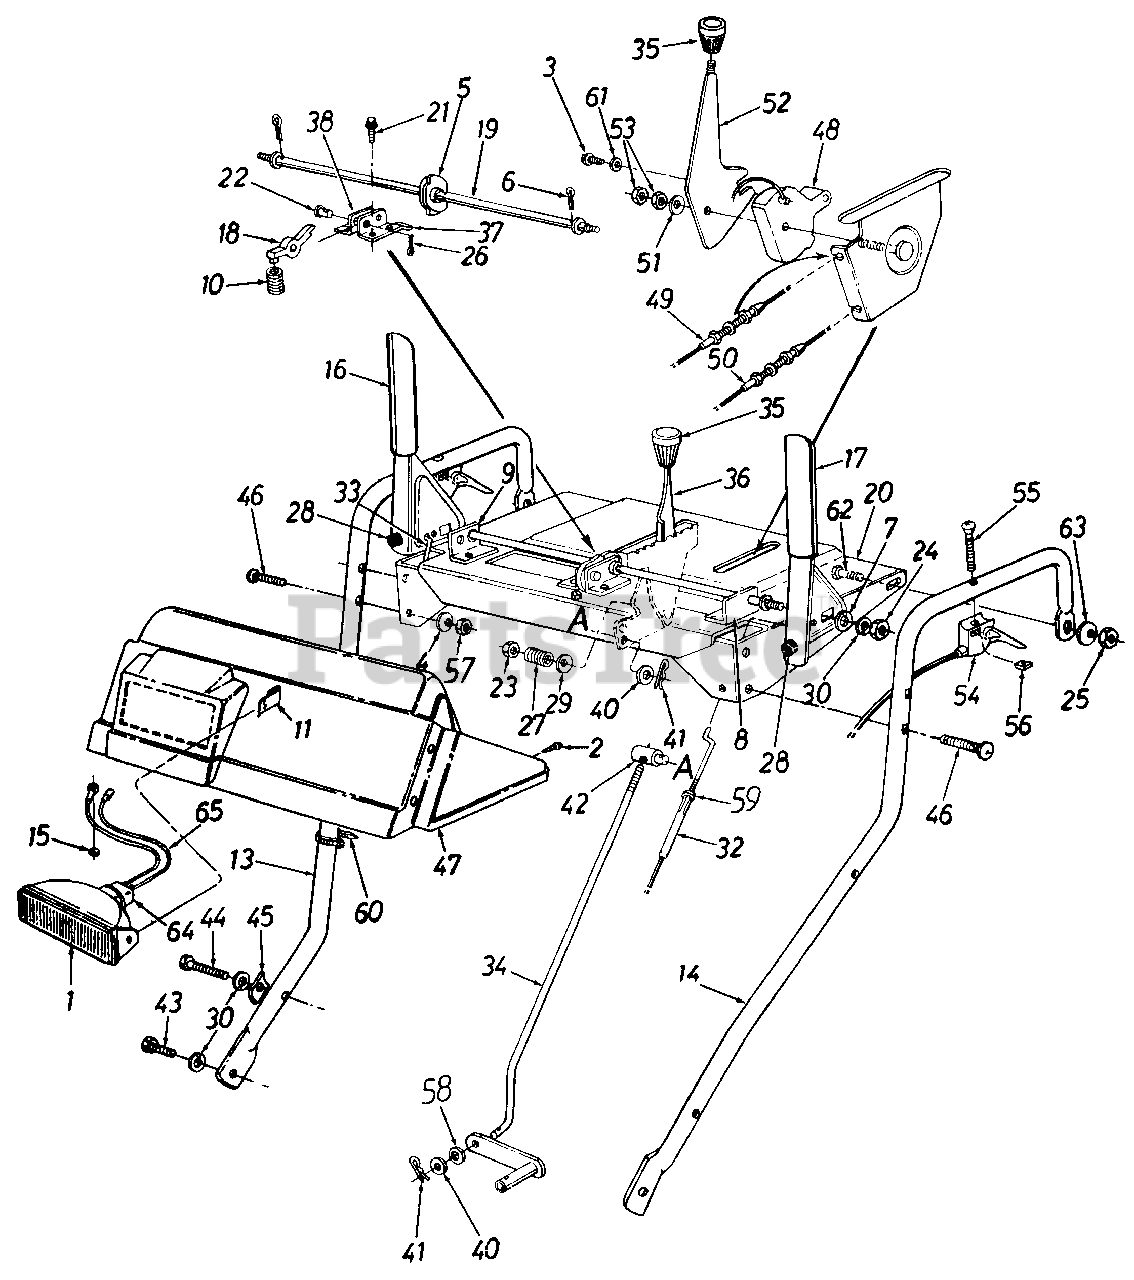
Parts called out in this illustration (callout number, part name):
1	Lamp Housing w/Lens
2	Truss Mach. B-Tap Scr. #10 x .5
3	Hex AB-Tap Scr. 1/4 x .62" Lg.
5	Cam Handle Lock
6	Cotter Pin 3/32" Dia. x .75" Lg.
7	Washer (Special) .72" O.D.
10	Compression Spring
11	Retaining Clip
13	Handle-R.H.
16	Engagement Handle-R.H.
17	Engagement Handle-L.H.
18	Pawl Handle Lock
22	Clevis Pin .437" Dia. x .65" Lg.
23	Hex Ins. L-Nut 3/8-24 Thd.
24	Hex Nut 5/16-18 Thd.
25	Hex Nut 1/4-20 Thd.
26	Cotter Pin 3/32" Dia. x 1" Lg.
27	Compression Spring
28	Rubber Bumper
29	Bell-Wash. .38" I.D. x .88" O.D.
30	L-Wash. 5/16" I.D.
32	Auger Clutch Cable
33	Drive Clutch Cable
34	Shift Rod
35	Shift Knob
36	Shift Handle
40	Fl-Wash. .344" I.D. x .62" O.D.
41	Internal Cotter Pin 5/16" Dia.
42	Ferrule
43	Hex Bolt 5/16-18 x .62" Lg. (Special)
44	Hex Bolt 5/16-18 x 1.75" Lg.
45	Handle Tab
46	Curved Carr. Bolt 5/16-18 x 1.5" Lg.
48	Cable Guide
49	Chute Control Cable
50	Chute Control Cable w/Clip
51	Bell-Wash. .325" I.D. x .93" O.D.
53	Hex Cent. L-Nut 5/16-18 Thd.
54	Track Steer Cable w/Trigger
55	Oval C-Sunk Hd. Scr. 10-24 x 1.375" Lg.
56	Flat Weld Nut #10-24 Thd.
57	Hex Nut 5/16-18 Thd.
58	Spr. Wash. .32" I.D. x .62" O.D.
59	Hex Nut #10-24 Thd.
60	Cable Tie
61	Washer (Special) 1.25" O.D.
62	Hex Bolt 1/4-20 x .85" Lg.
63	Bell-Wash. .265" I.D. x .75" O.D.
64	Bulb
65	Wire Harness
